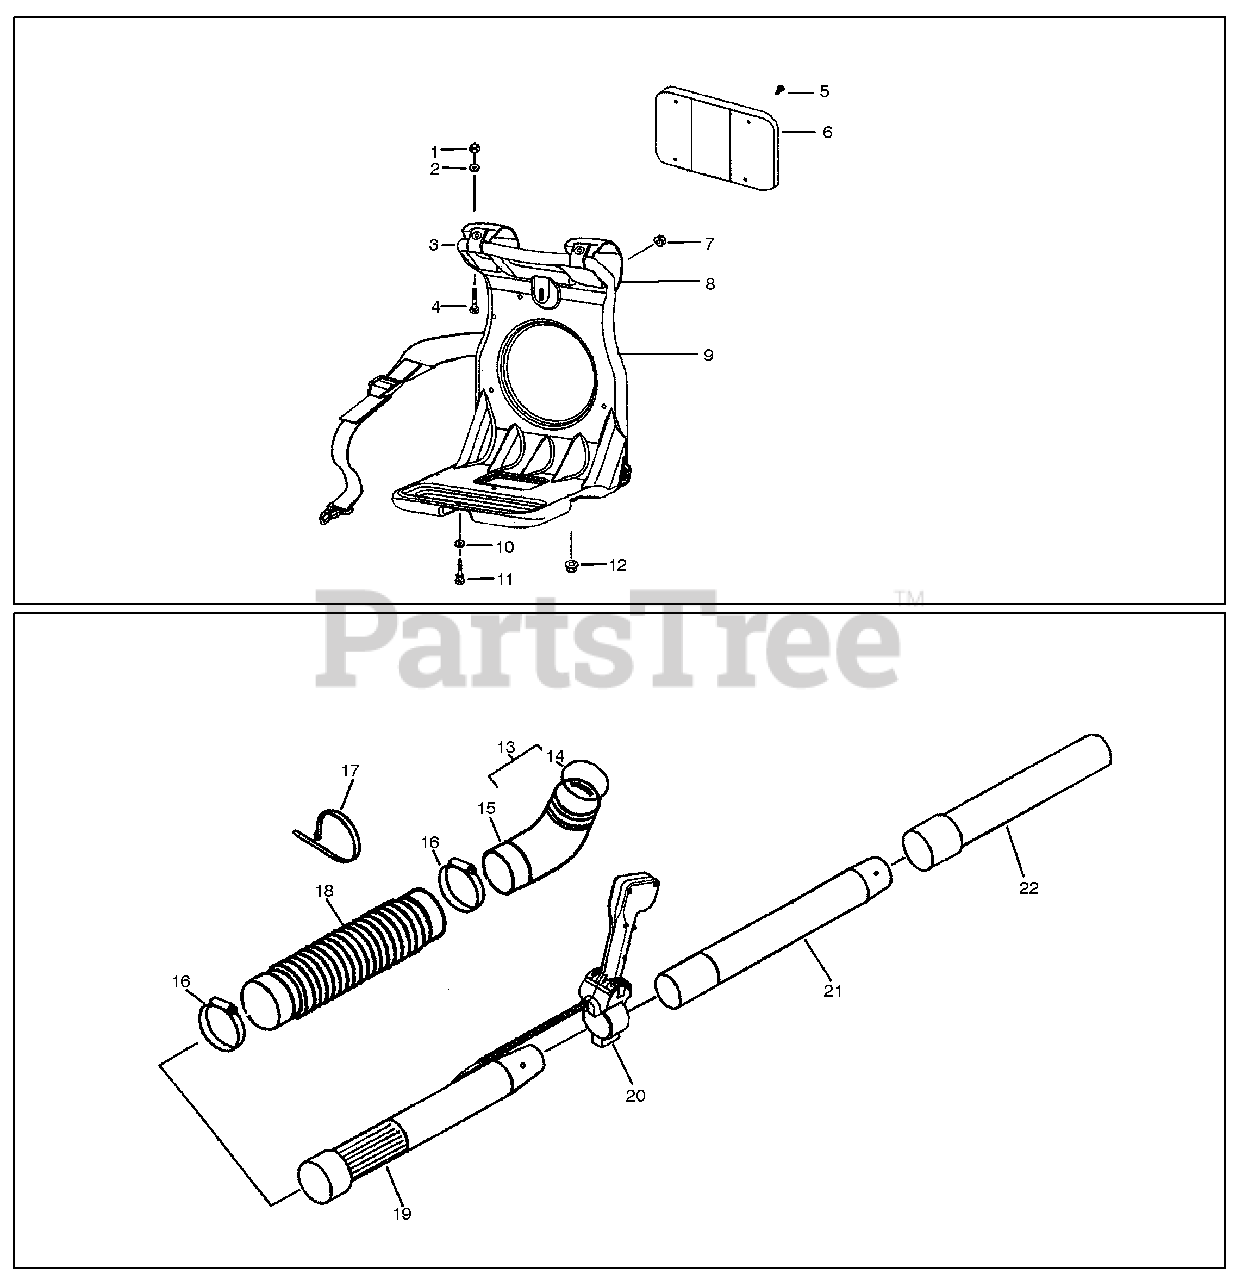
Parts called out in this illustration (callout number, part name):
1	Nut-Nylon Flange
3	Shoulder Band
4	Screw-Truss
6	Pad-Knapsack
8	Shoulder Band
9	Frame-Knapsack
11	Screw m6x25
13	Elbow Pipe C.P.
15	Elbow Pipe
16	Hose Band
17	Wire Band
18	Flex Pipe
19	Base Pipe
20	Assy-Throttle Lever
21	Middle Pipe
22	Bend Pipe
